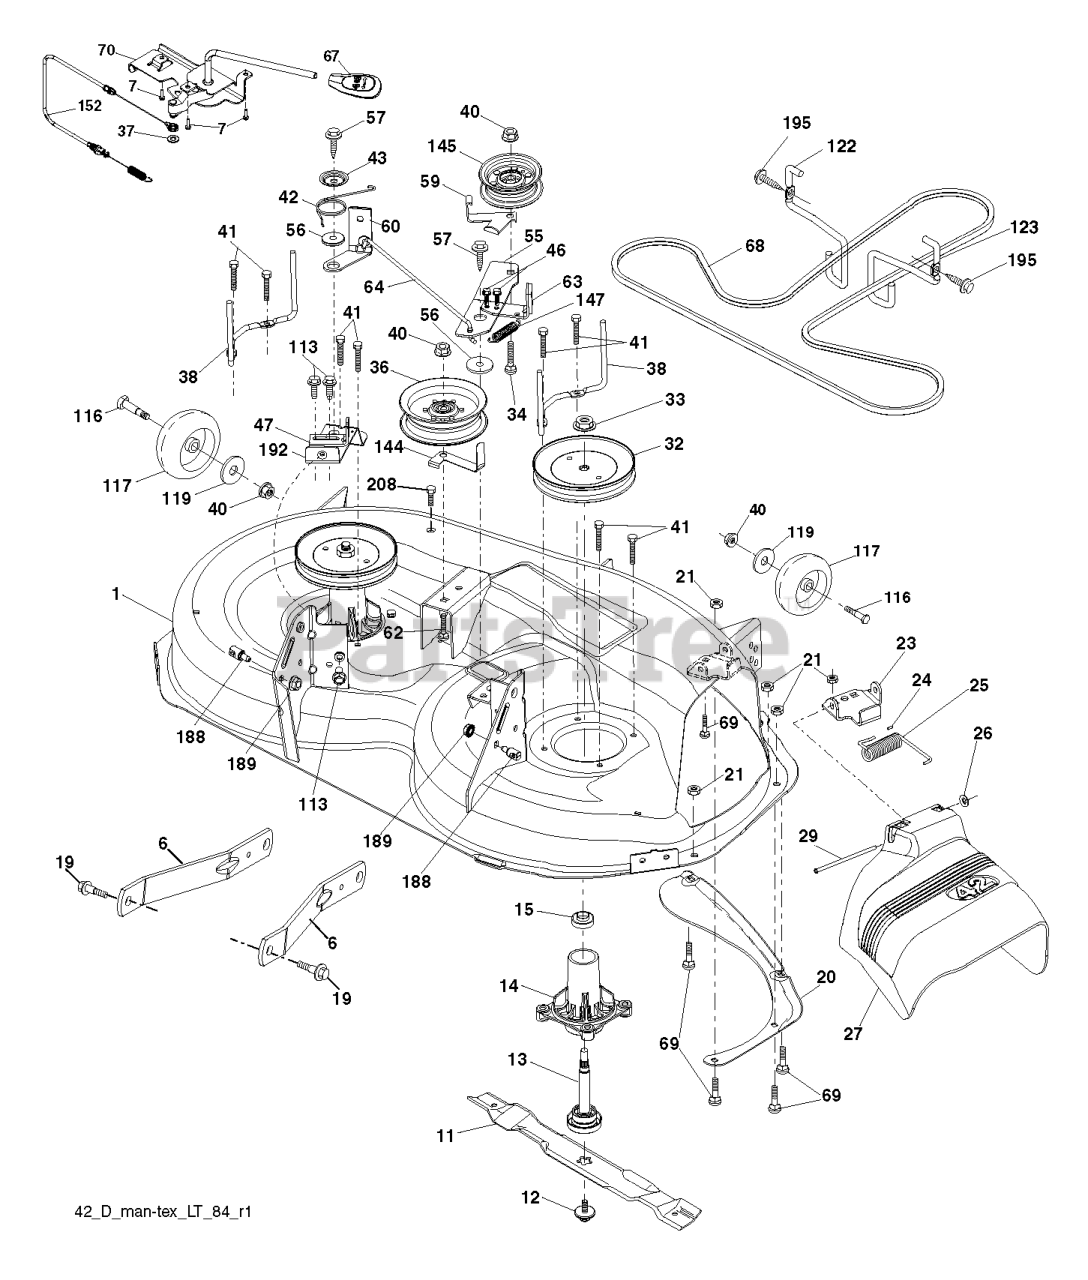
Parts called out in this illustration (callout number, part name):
1	DECK.WELDMENT.42"
6	ARM.SUSPENSION.MOWER.R
7	SCREW.#10 X 0.750.BOS (2 2)
11	42" HI-LIFT BLADE
12	SCREW.SEMS.7/16-20X1.HEX.HEAD
13	SHAFT ASM.MNDRL.N/GREASEABLE
14	HOUSING.MANDREL.4PT.
15	BEARING.MANDREL.TOP.EXTENDED
19	BOLT.SHOULDER
20	BAFFLE.VORTEX
21	Locknut, Hex w/Insert 5/16-18 Unc
23	BRKT.DEFLECTOR.38"2005+
24	Cap Sleeve 80x 112 Blk Mower (AYP part number)
25	SPRING.TORSION.DEFLECT
26	Nut Push Phos & Oil (AYP part number)
27	SHIELD.DEFLECTOR.MOWER.42"BLAC
29	Rod Hinge 42" 6 75 Wlg (AYP part number)
32	PULLEY.MANDREL.5.438.PD
33	NUT.FLANGE.LOCK.TOP
34	Bolt Carriage 3/8-16 x 1-1/2 (AYP part number)
36	PULLEY.IDLER.2006
37	Washer 13/32 x 1-3/16 x 12 Gauge (AYP part number)
38	KEEPER.42.BELT.MANDREL.PULLEY
40	NUT LOCK FLG 3/8-16 UNC
41	BOLT.HEX.WASHR.HED.313-18X1.19
42	SPRING.TORSION.BRAKE
43	SRPING.TORSION.RETAINE
46	Screw Hex Thd Cut 1/4-20x5/8 T (AYP part number)
47	BRKT.CLUTCH.CABLE
55	IDLER.ARM.42"
56	SPACER.RETAINER
57	SCREW 3/8-16X1
59	Guard TUV Idler (AYP part number)
60	ARM BRAKE MOWER
62	Bolt, Carr. 3/8-16 x 1-3/4 Gr. 5 (AYP part number)
63	ARM BRAKE MOWER
64	LINK BRAKE
67	HANDLE.CLUTCH.CABLE.LT
68	BELT.DECK.DRIVE.42"
69	Bolt, Carriage 5/16-18 UNC x 5/8 (AYP part number)
70	CLUTCH.ASM.MANUAL.YT.PREDATORQ
113	BOLT.5/16HEX.WHS.HD
116	Bolt, Shoulder (AYP part number)
117	WHEEL.GAUGE.RALLY.NARROW
119	Washer 3/8 x 7/8 x 14 Ga. (AYP part number)
122	KEEPER BELT ENGINE LH
123	KEEPER BELT RH
144	KEEPER.BELT.MOWER
145	PULLEY.IDLER.48"PRIMARY
147	RETURN SPRING
152	CABLE.MECHANICAL.CLUTCH
188	STUD.FASTNER.W/ANTI-ROTATE
189	NUT LOCK HEX FLANGE 5/16-18
192	BRKT.BRAKE.STAND.LH.
195	SCREW, 3/8-16X3/4
208	SCREW 3/8-16X1/2
